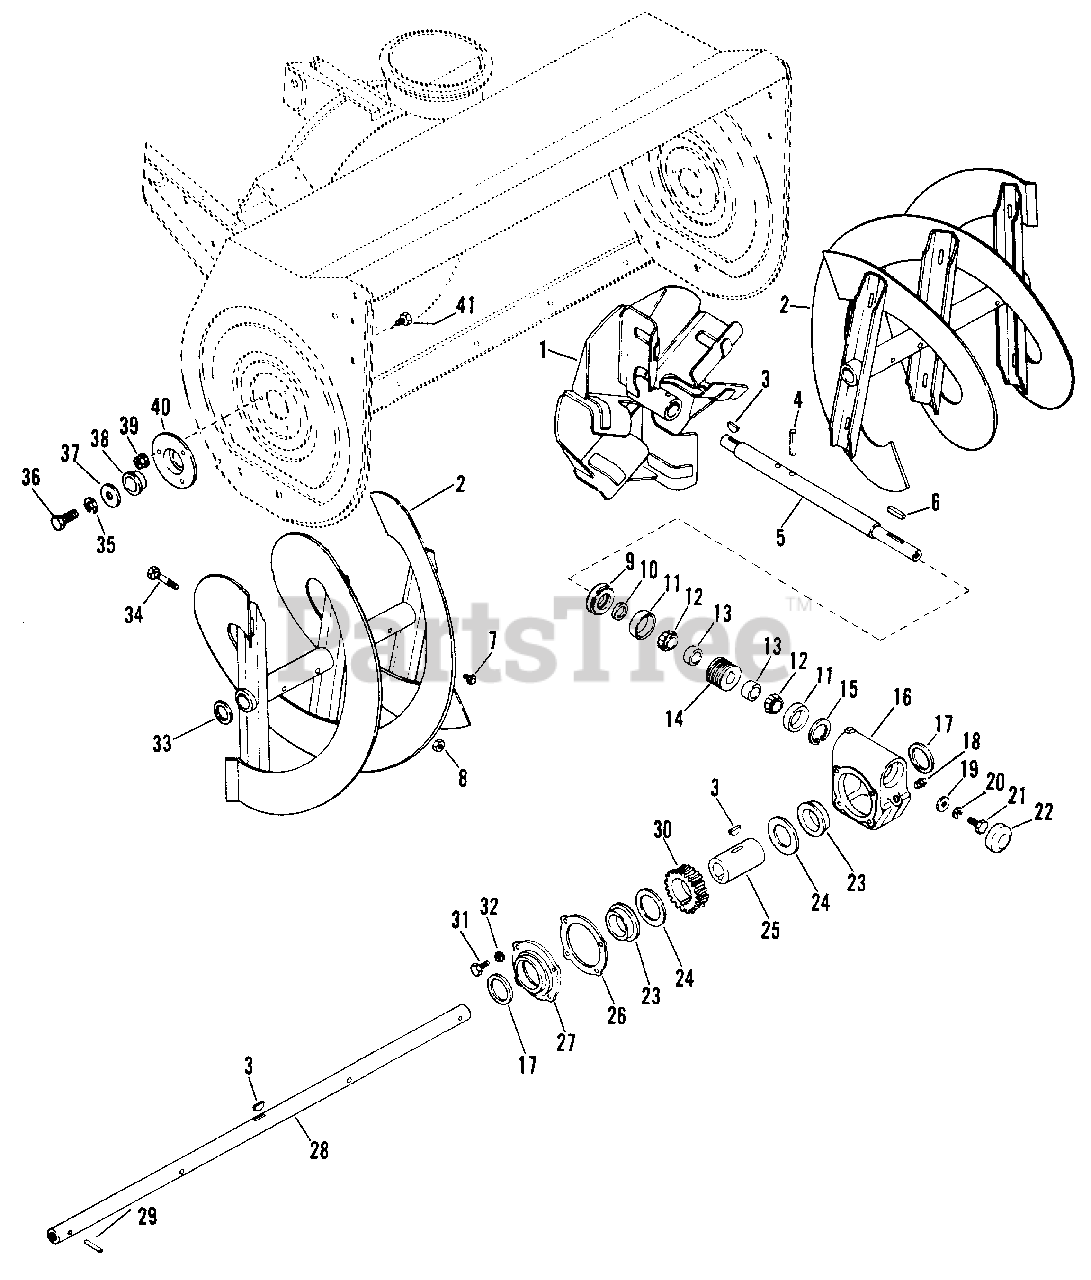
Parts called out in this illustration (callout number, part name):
1	Fan
2	Rake, Right
2	Rake, Left
3	Key, Woodruff .250x.875 HRD #A
4	Pin, Roll .312x1.75
5	Shaft, Worm
6	Key, Straight SAE 1035
7	Fitting, Lube 1/4-28
8	Nut, Lock 5/16-18
9	Plug, Adjustment
10	Seal
11	Cup, Bearing
12	Cone, Bearing
13	Spacer, Bearing
14	Worm
15	Snap Ring, Internal
16	Gear Case
17	Seal, 1-5/8 Nom.
18	Plug, Pipe
19	Washer, Flat .344x.688x.065
20	Washer, Lock 5/16 SP
21	Bolt, Hex 5/16-18x.75
22	Cap, Dust
23	Bushing, Flange 1.62 x1.87x11
24	Washer, 1.625x2.500x.012
25	Shaft, Gear Case
26	Gasket
27	Cover, Gear Case
28	Shaft, Rake
29	Pin, Spring .187x.500
30	Gear, Worm
31	Bolt, Hex 1/4-20x.875
32	Washer, Lock 1/4
33	Washer, 1.00x1.50x.06
34	Bolt, Shear
35	Washer, Lock 1/2
36	Bolt, Hex 1/2-13x1.00
37	Washer, Flat .515x1.441x.1
38	Bushing, Flange 1.00x1.125x.625
39	Nut, Lock 1/4-20
40	Support, Bearing
41	Bolt, Rib Neck 1/4-20x.50
